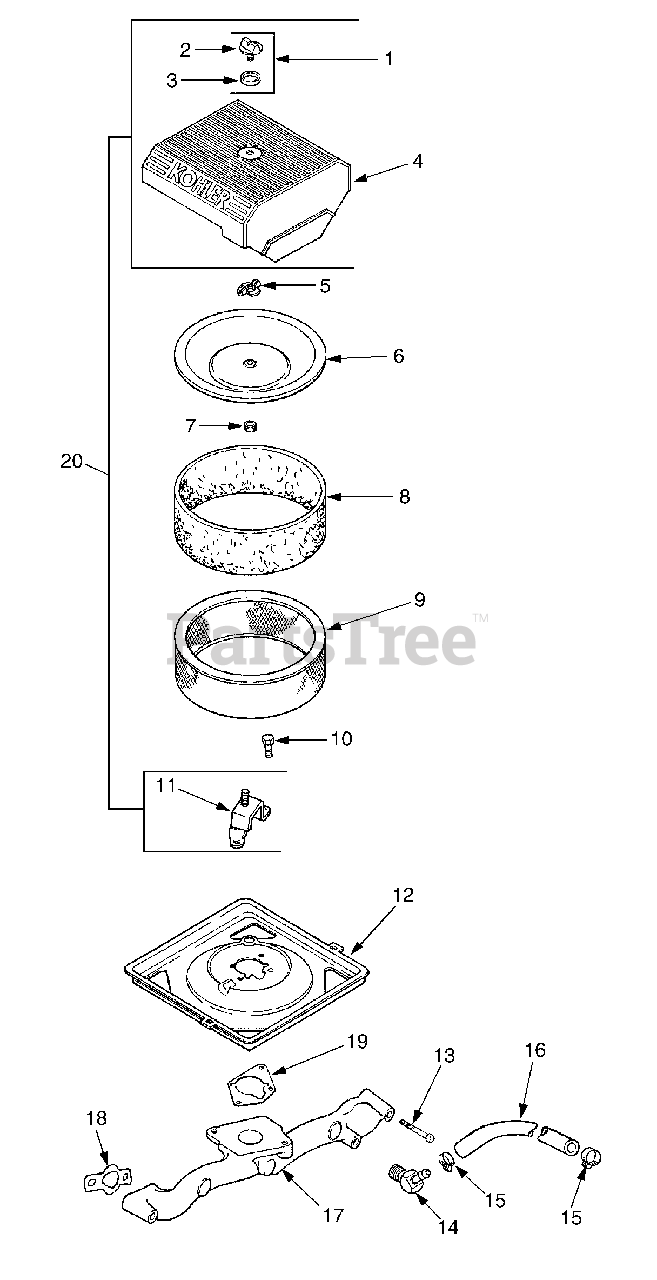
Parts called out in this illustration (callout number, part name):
1	Kit, Knob w/Seal
3	Seal, Air Cleaner Cover Knob
4	Cover, Air Cleaner
6	Cover, Inner Air Cleaner
7	Seal, Inner Air Cleaner
8	Precleaner, Element
9	Element, Air Cleaner
10	Screw, Hex Flange M6 x 1.0 x 16
11	Bracket, Air Cleaner Base
12	Base, Air Cleaner
13	Screw, Hex Flange M6 x 1.0 x 55
14	Connector, Hose 45°.
15	Clamp, Hose
16	Line, Fuel 5"
17	Manifold, Intake
18	Gasket, Intake Manifold
19	Gasket, Air Cleaner Base
20	Kit, Air Cleaner Cover
